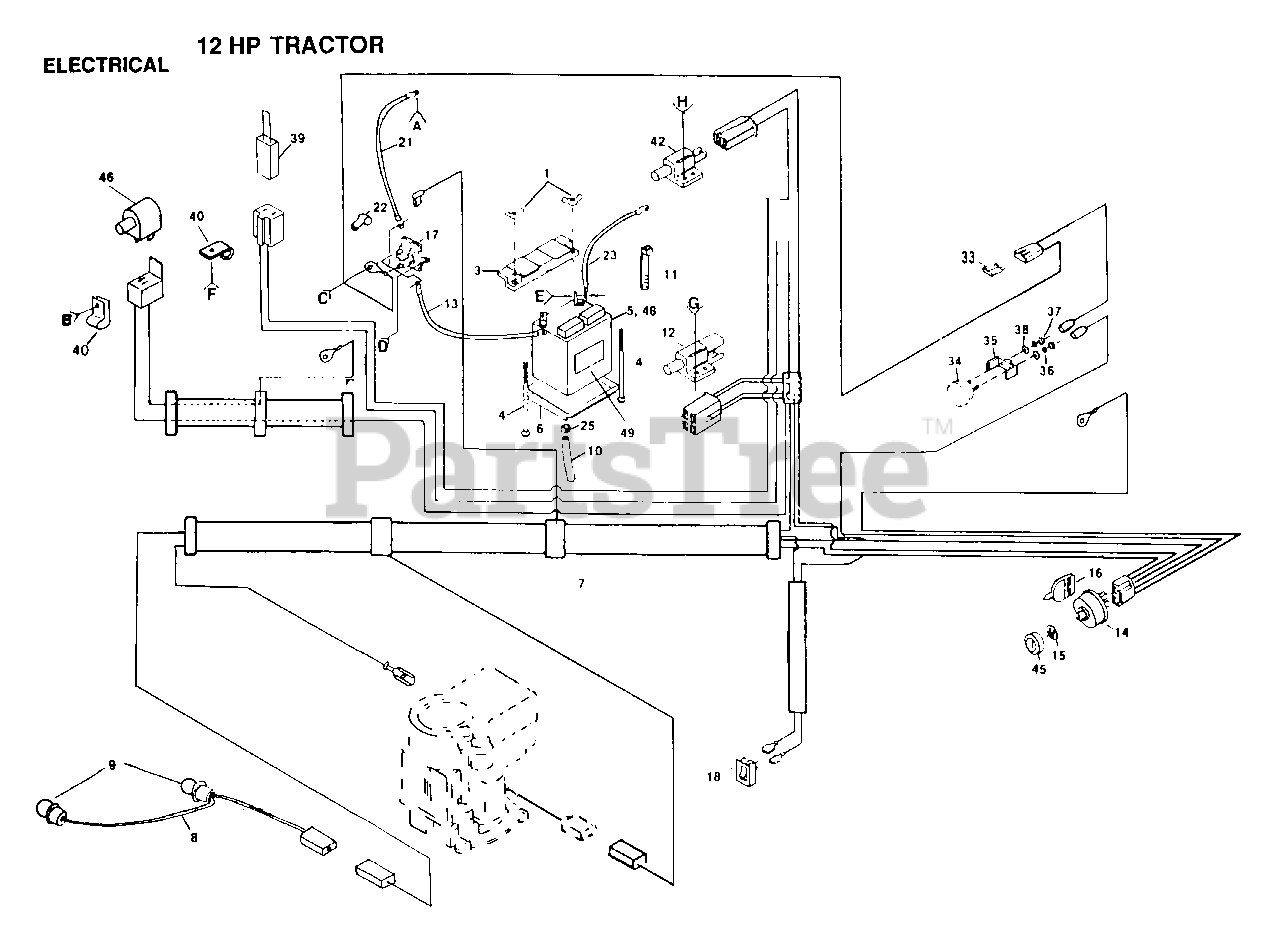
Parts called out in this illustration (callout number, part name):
4	BOLT
6	"TRAY T, BATTERY"
7	IGNITION HARNESS
8	HARNESS T
11	WIRE TIE
12	SWITCH INTERLOCKT
13	CABLE-BATTERY T
16	KEY
18	SWITCH LT
21	"CABLE T, BATTERY"
23	CABLE T
25	HOSE CLAMP T
33	FUSE HYT
34	AMMETER T
38	WASHER
40	CLIPT
42	SWITCH-INTER. GT
46	SWITCH SEAT
48	"CAP,BATTERY "
49	DECAL
